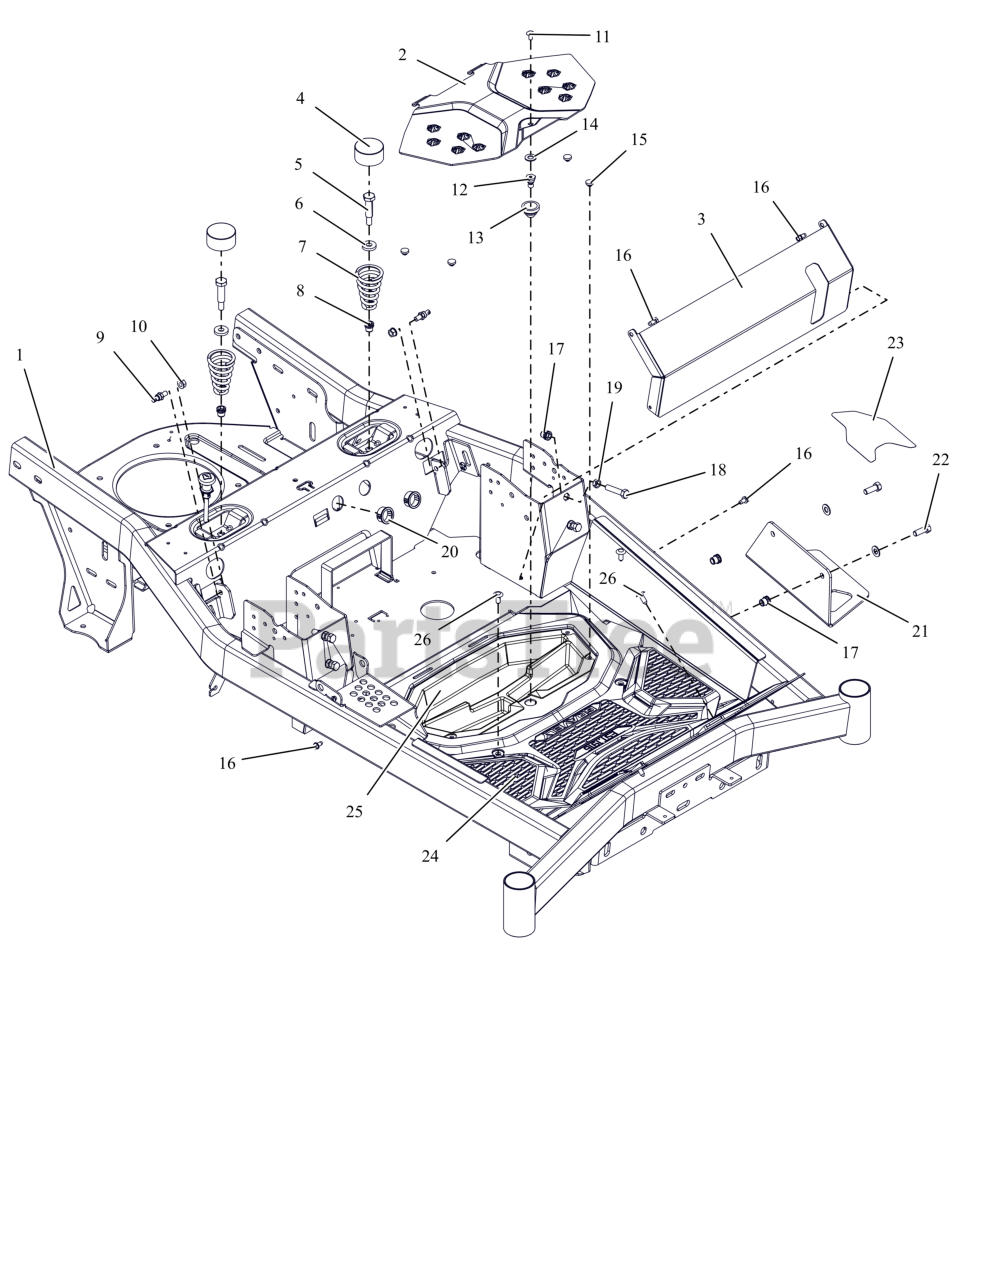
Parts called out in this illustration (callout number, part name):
1	KIT-GRAVELY FRAME W/ DECALS
2	KIT-GRAVELY ACCESS PLT W/DECAL
3	PLATE- FRONT KICK-RED
5	BLT-SHLDR .50X1.50 .375-16 ZCC
6	WSHR, FLT .406X1.00X.188 ZCC
7	SPRING, SEAT
8	NUT,THD,INSERT .38-16 ZC120
9	COUPLER, DAMPER MOUNT
10	NUT-LK-TOP-FLG .312-18 GF ZCC
11	BLT, RHSSN.25-20X.500 G5 ZCC
12	STUD, BALL FEMALE .250-20 THREAD
13	COUPLING, RUBBER PUSH-IN
14	WSHR,FLT .406X.812X.065 ZCC
15	BUMPER GROMMET
16	SCR-TAP .25-20X.50 HWH ZCC
17	NUT,THD,INSERT .38-16 ZC120
18	BLT, HEX .38-16X1.75F G5 ZCC
19	NUT-JAM .375-16 G2 ZCC
20	BSHG, PANEL SNAP .937X1.11X.56
22	BLT, HEX .38-16X1.00 G8ZCCEP30
23	GRIP- TAPE - STEP-GRAVELY
24	MAT- RUBBER FOOTBOARD
25	INSERT- GRAVELY STORAGE
26	XMAS TREE FASTNER-BLACK
